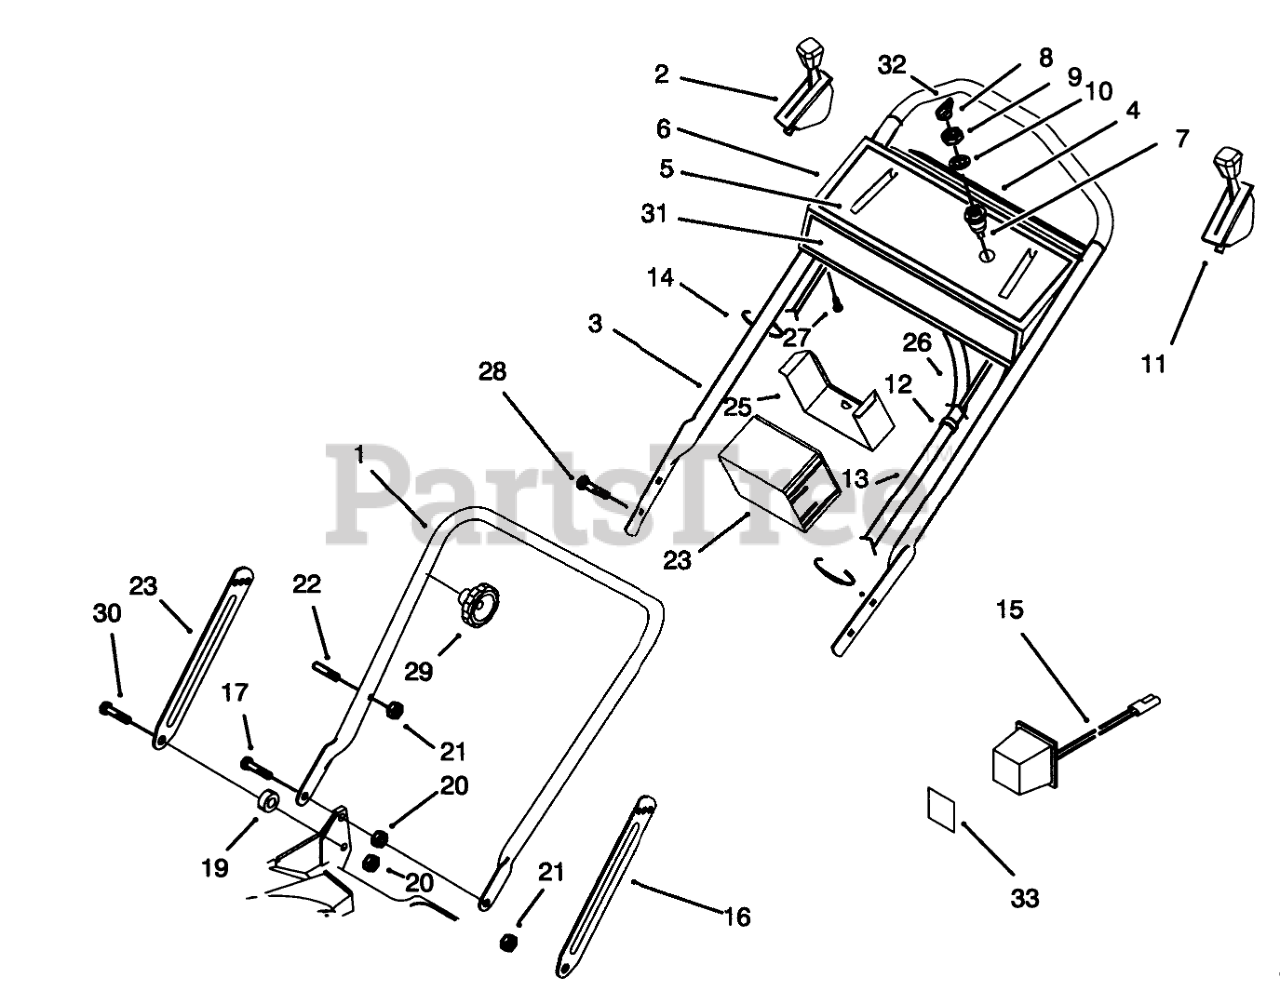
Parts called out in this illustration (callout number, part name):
1	ASM-Handle
2	Control-Ground Speed
3	Handle-Upper
4	DECAL-PANEL, DANGER
5	Decal-Instructions
6	Panel-Control (Incl. Ref. #4, 5, & 31)
7	STARTER SWITCH ASM
8	KEY-IGNITION
9	NUT-HH
10	WASHER-TOOTH, INTERNAL
11	THROTTLE CONTROL
12	FITTING-RING
13	CONTROL CABLE COVER
14	TIE-CABLE
15	Charger-Battery
16	Latch-Handle
17	SCREW-SHOULDER
18	SCREW-SHOULDER
19	SPACER
20	NUT-LOCK, NI
21	NUT-LOCK, NI
22	HANDLE PIN
23	BATTERY ASSEMBLY
25	Retainer-Battery
26	Harness-Wire
27	10-16X1/2 SHWH SCREW
28	SCREW-HANDLE
30	Latch-Handle
31	DECAL - FRT PANEL
32	Grip-Foam
33	DECAL - CAUTION F/W
